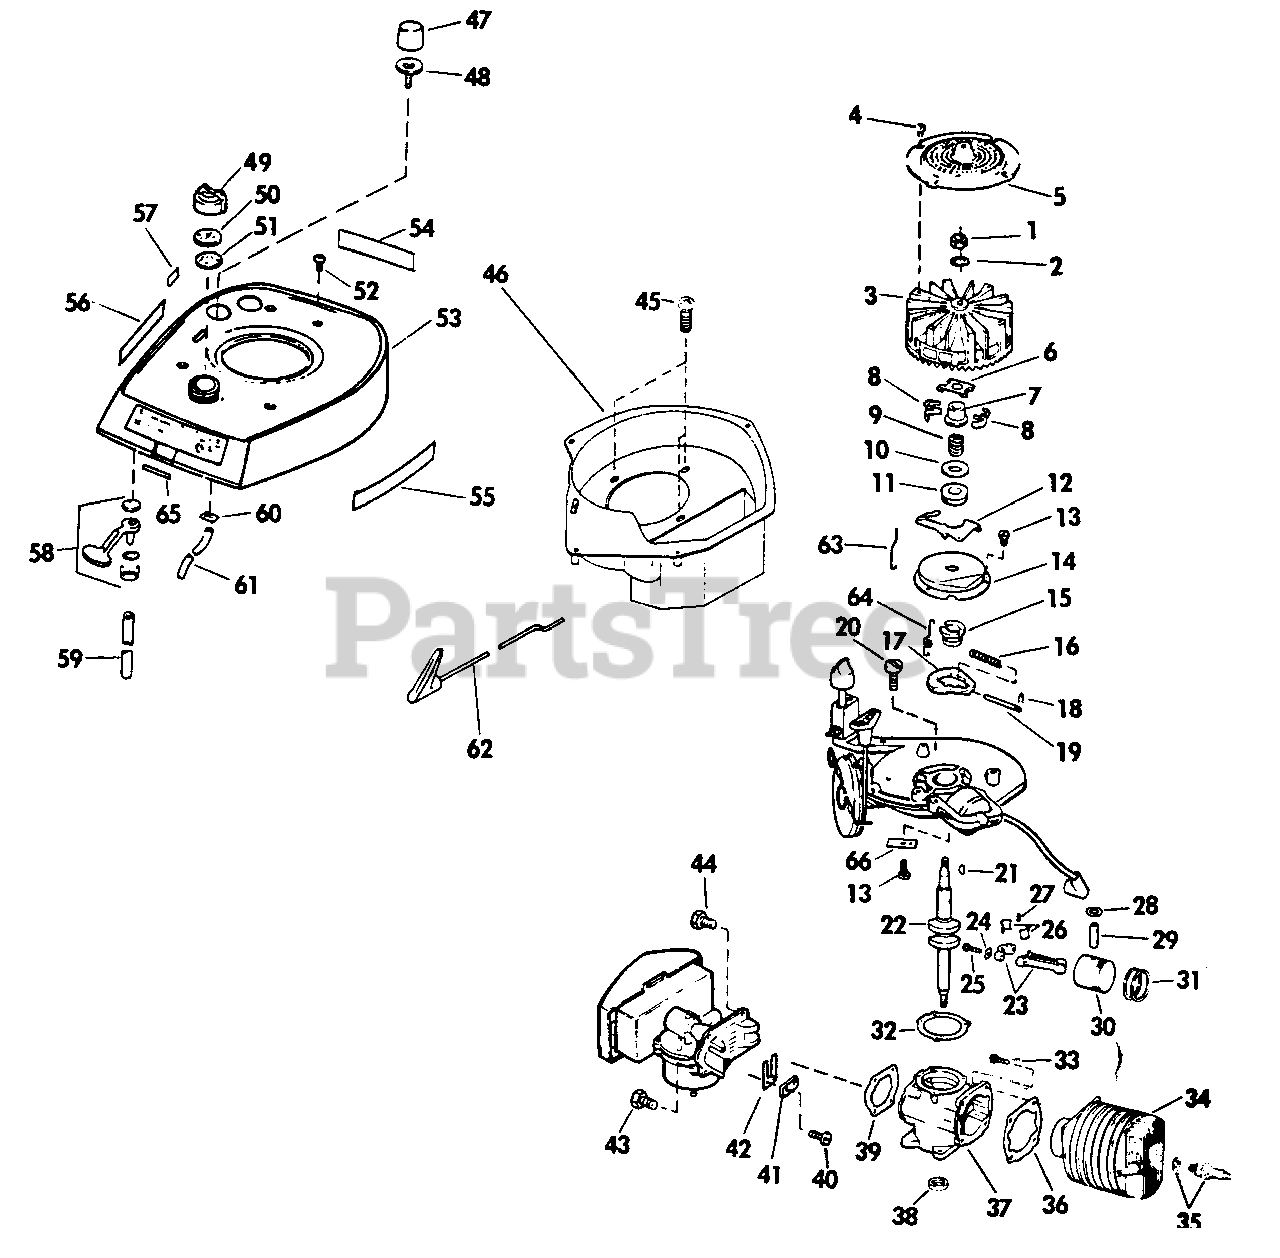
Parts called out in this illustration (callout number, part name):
1	Nut-Flywheel
2	Lockwasher-Flywheel
3	Flywheel & Screen Assy.
4	Screw-Thd. Cutting
5	Screen & Cup
6	Yoke-Governor
7	Collar-Governor
8	Weight-Governor
9	Spring-Governor
10	Thrust Washer
11	Collar-Thrust
12	Lever-Governor
13	Screw-Attach. Dust Cover, Rod Tab
14	Dust Cover
15	Cam-Spark Advance
16	Spring-Spark Advance
17	Flyweight-Spark Advance
18	Retainer-Spring
19	Pin-Spark Advance
20	Scr.-Arm. Pl. to Crankcase
21	Key-Crankshaft
22	Crankshaft
23	Connect. Rod Assy.
24	Lockpl.-Connect. Rod Scr.
25	Screw-Connect. Rod
26	Liners-Connect. Rod (Set)
27	Needle Brg. Set
28	Retaining Ring
29	Wrist Pin
31	Ring Set
32	Gasket-Crkc. to Arm. Pl. .005 in.
32	Gasket-Crkc. to Arm. Pl. .010 in.
33	Screw-Cyl. to Crankcase
34	Cylinder and Sleeve Assembly
35	Spark Plug and Gasket
36	Gasket-Cyl. to Crankcase
37	Crankcase and Seal Assy.
38	Oil Seal
39	Gasket-Reed Plate
40	Screw-Machine
41	Plate-Back-up
43	Screw-Reed Pl. to Crkc.
45	Screw-Air Baffle
46	Air Baffle
47	Bulb-Primer
48	Base-Primer
49	Cap, Gas Tank
52	Screw-Cover Mtg.
53	Cover, Engine
54	Decal-Lawn-Boy
55	Decal-R.H. 21"
55	Decal-R.H. 19"
56	Decal-L.H. 21"
56	Decal-L.H. 19"
57	Decal-Fingertip
58	Shut-off Valve
59	Fuel Hose
60	Fastener
61	Tube, Primer
62	Knob & Rod
63	Rod Governor
64	Spring-Variable Speed
65	Spring Bar
66	Tab-Rod
